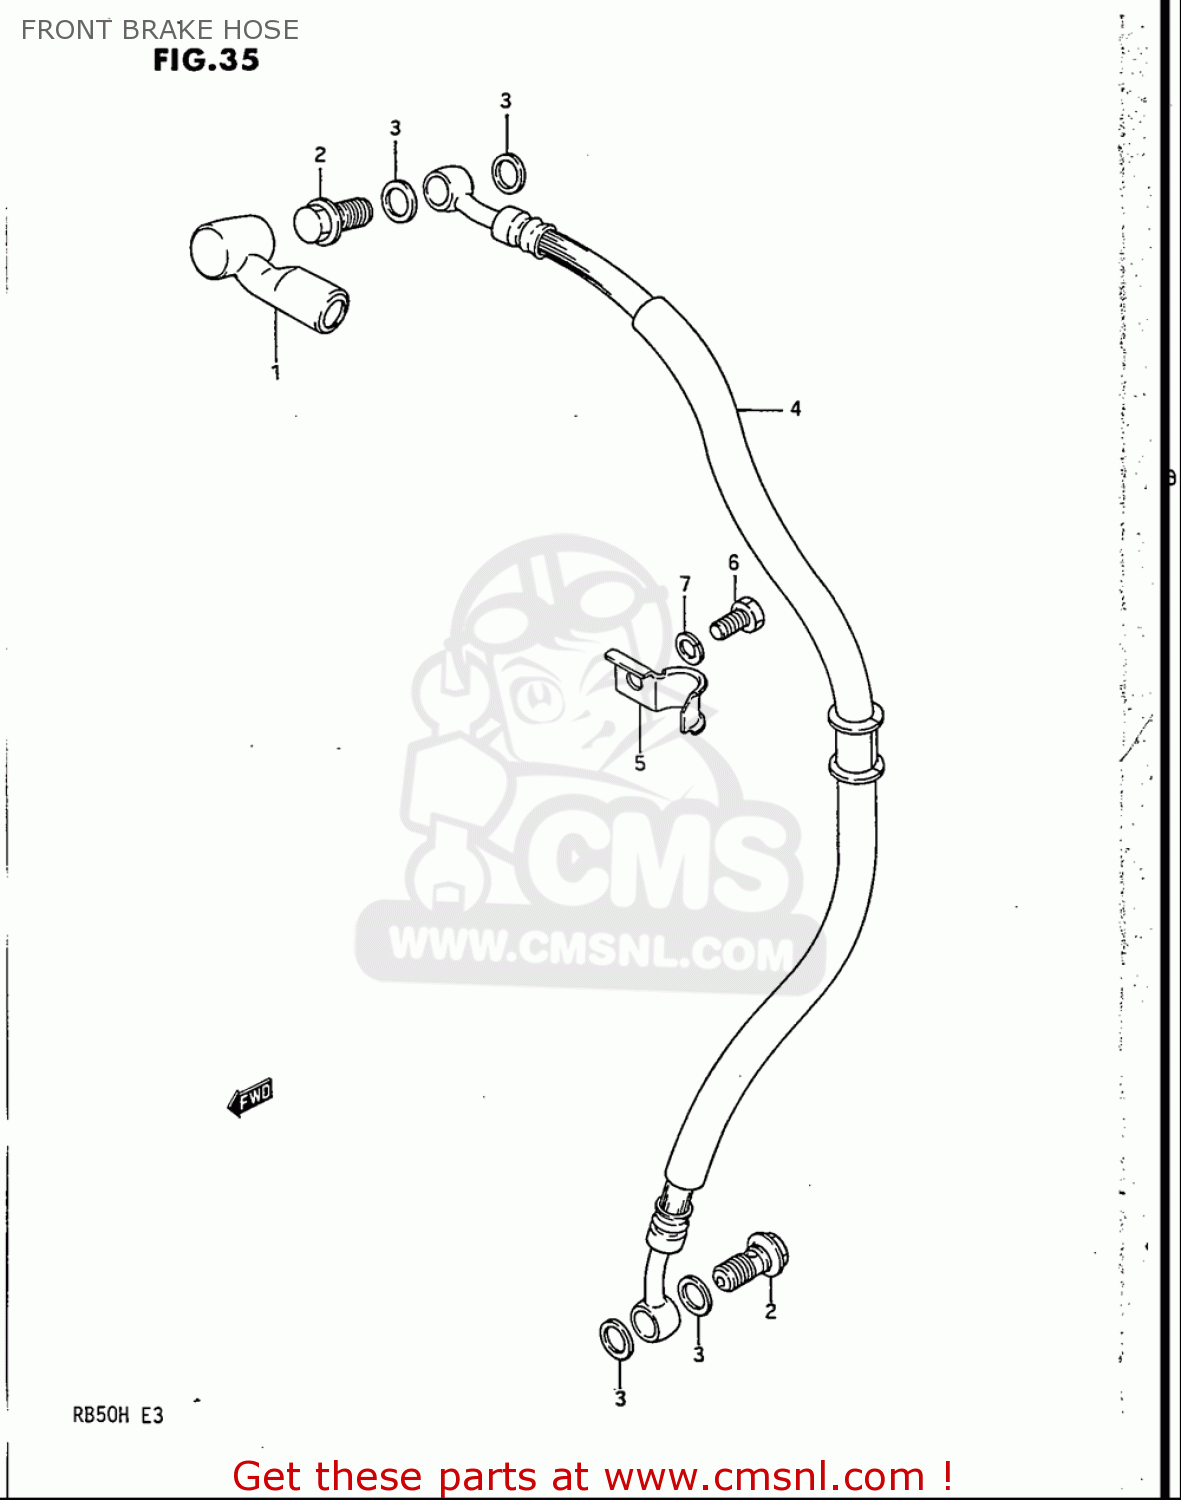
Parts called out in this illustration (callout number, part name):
1	BOOT,MASTER CYLINDER
2	BOLT UNION
3	WASHER(10X15X1.5)
6	BOLT
7	WASHER,LOCK
